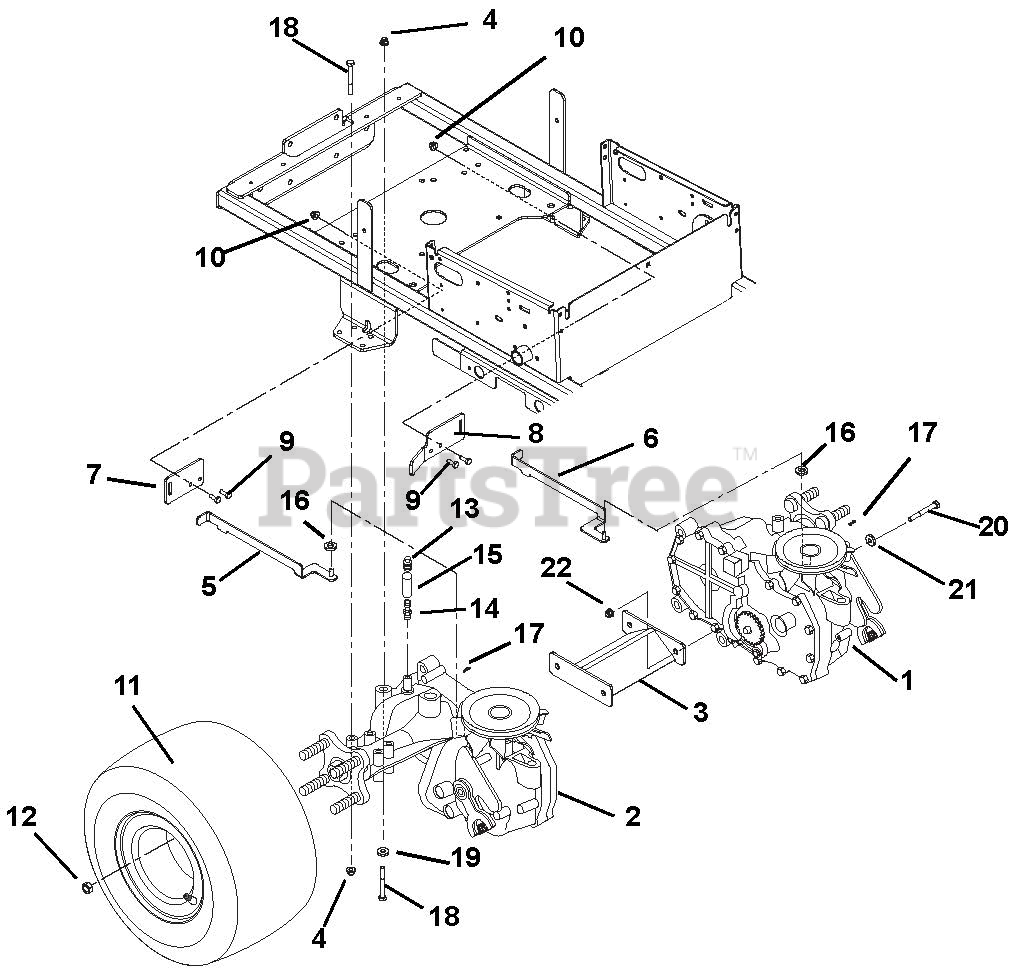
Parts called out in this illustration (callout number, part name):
1	EZT, LH TRANSAXLE (ZOOM)
2	EZT, RH TRANSAXLE (ZOOM)
3	WMT, TRANSAXLE SUPPORT
4	@NUT-LK-NYL-FLG .31-18 YWZC
5	WMT, DUMP VALVE (ZOOM-RH)
6	WMT, DUMP VALVE (ZOOM-LH)
7	BRACKET, DUMP VALVE
8	BRKT,DUMP VALVE/CLUTCH STOP
9	@BLT-HEX .25-20X.75 GR5 YWZC
10	NUT-LUG .50-20 YWZC
11	TIRE/WHEEL ASSY, 18X9.50-8 OFF
12	NUT-LUG .50-20 YWZC
13	CAP-VENT .50
14	FTG-STR .50 O-RING
15	HOSE - VENT
16	WSHR-FL-STL .265X.50X.087YWZC
17	PIN-HAIR INT .06X.18X.77
18	@BLT-HEX .31-18X2.75 GR5 YWZC
19	WSHR-FL-STL .328X.87X.179 YWZC
20	@BLT-HEX .38-16X2.50 GR5 YWZC
21	WSHR-FL-STL .406X1.00X.188 YWZ
22	@NUT-LK-NYL-FLG .38-16 YWZC
